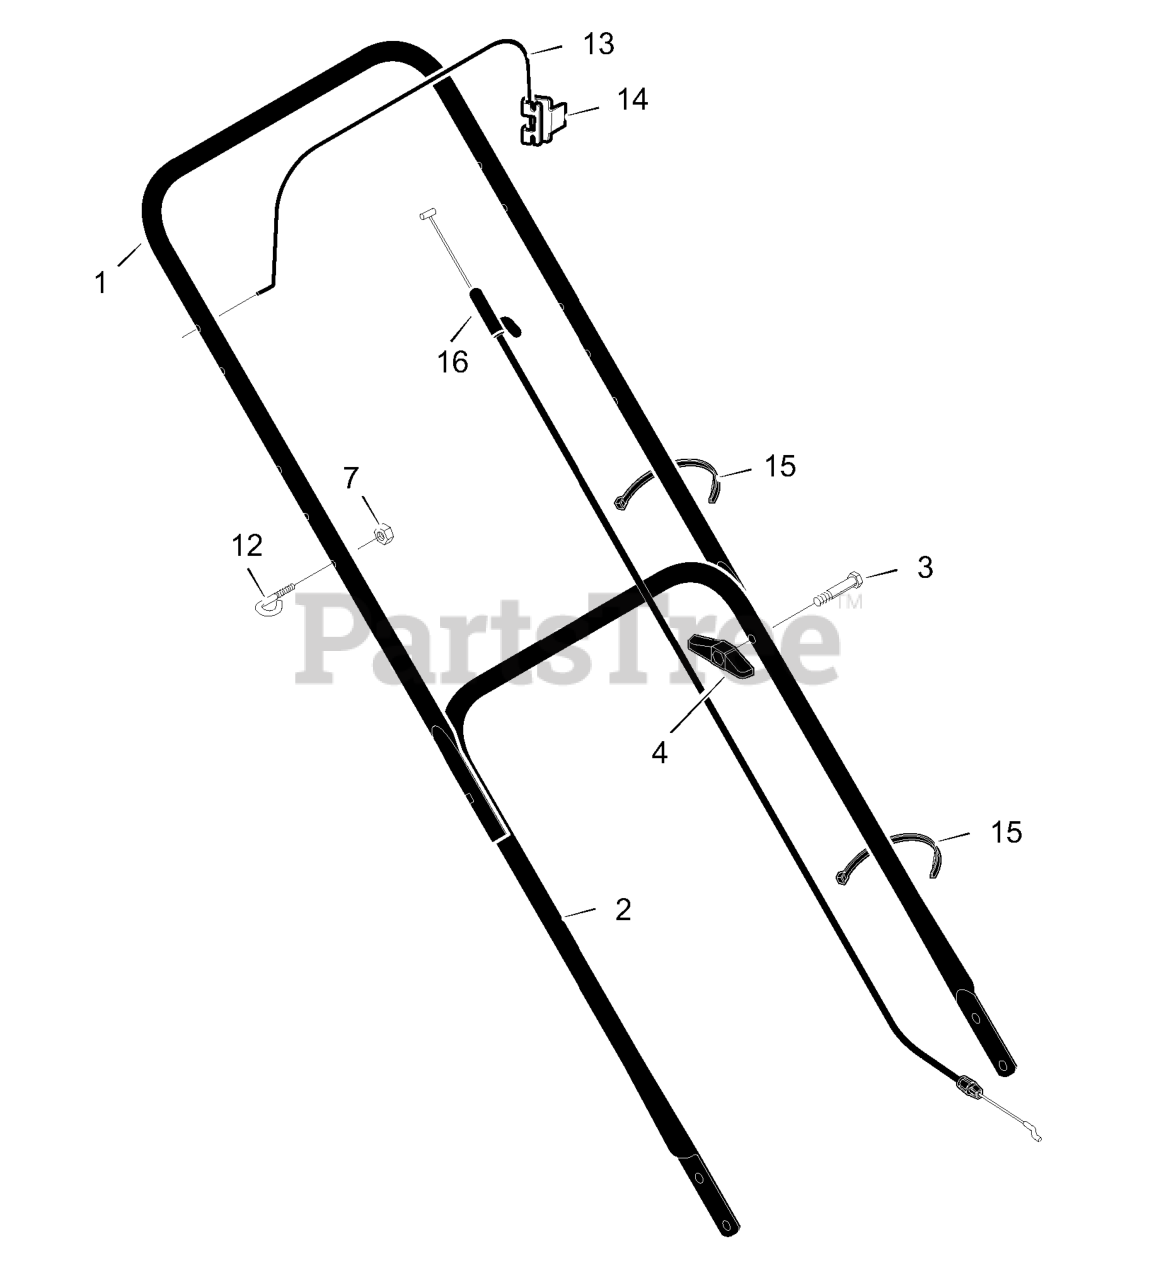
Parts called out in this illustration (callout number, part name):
1	Handle, Upper (Black)
2	Handle, Lower (Black)
4	Knob, Plastic
7	Locknut
12	Guide, Rope
13	Engine Stop Lever
14	Bracket, Stop Lever
15	Fastener, Cable
16	Engine Stop Cable
